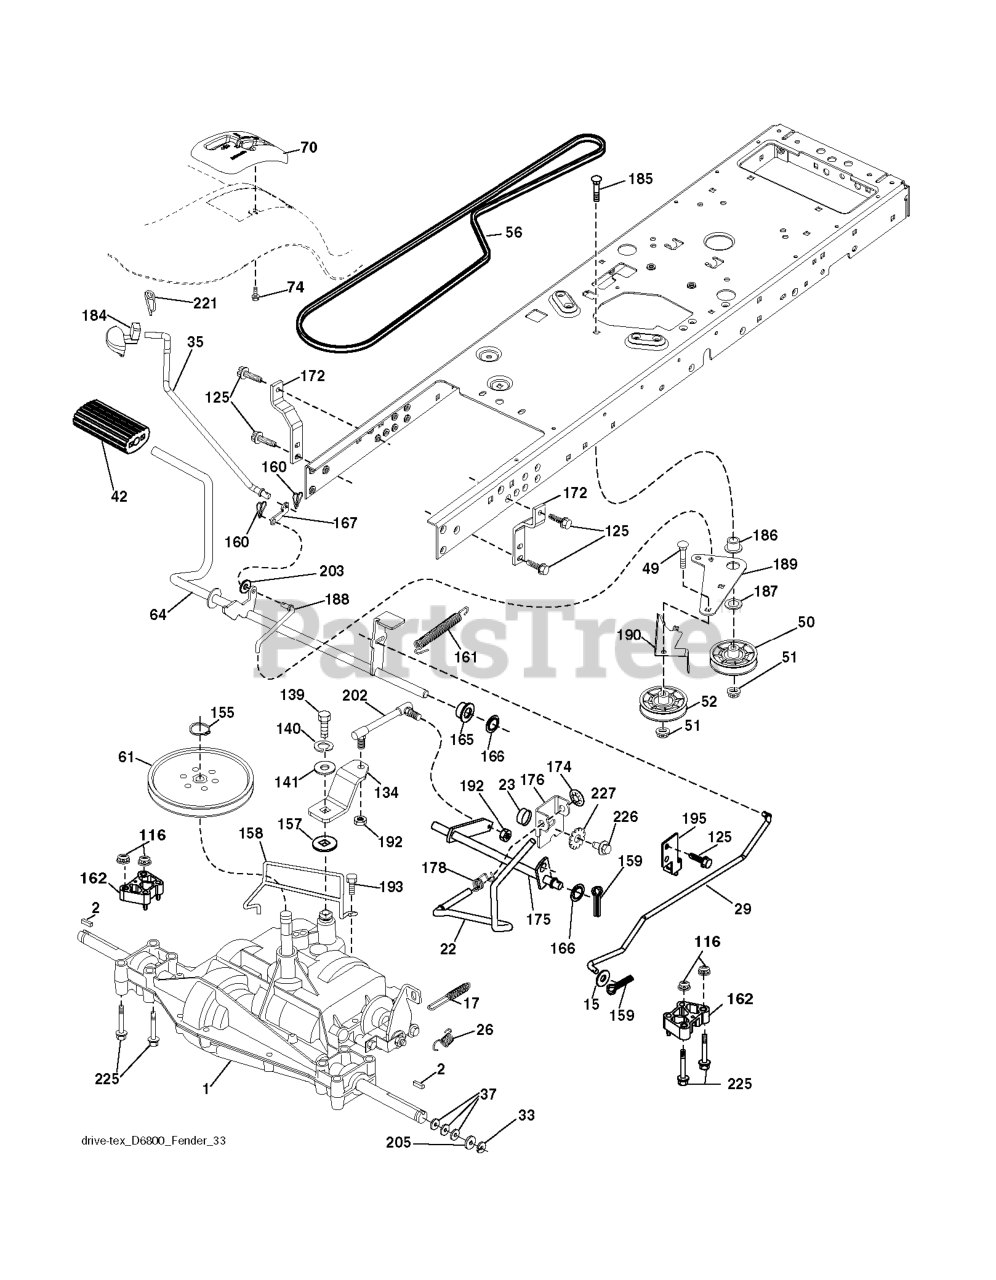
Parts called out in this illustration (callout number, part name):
2	SQUARE KEY
15	WASHER
17	SPRING.BRAKE.PEERLESS.TEX
22	ROD.SHIFT.FENDER.TLT.2006
23	KNOB.DUCKHEAD.1/2
26	SPRING.BRAKE.RTN.GR.DR
29	ROD.BRAKE.PEERLESS
35	ROD.CNTRL.PARK.PREDATOR.LT.TEX
42	PEDAL COVER T
50	IDLER.FLAT.910.OFFSET
51	NUT LOCK FLG 3/8-16 UNC
52	IDLER.V-GROOVE.910.OFFSET
56	V-BELT.TRACTOR.DRIVE.P
61	PULLEY TRANS
64	SHAFT.ASM.PEDAL.BRAKE.
70	CONSOLE.SHIFT.STL.6SP.GREY
74	SCREW.HI-LO.CONSOLE
116	NUT LOCK HEX FLANGE 5/16-18
125	SCREW
134	ARM.SHIFT.
139	BOLT 1/4-28X3/4
140	LOCKWASHER
155	RETAINING RING LT
157	WASH-SHFT PLT LT
158	KEEPER.PMS.18/20.D4365
159	COTTER PIN
160	RETAINER CLIP
161	SPRING.RETURN.CLUTCH.2006
162	SPACER.TRANSAXLE.18&22
165	BUSHING.SHAFT.BRAKE.HAND
166	NUT.PUSH.625.2006
167	LATCH.BRAKE.SPRING
172	STRAP.TRQ.LH.GEAR.DRIV
174	NUT.PUSH.500.2006
175	SHAFT.ASM.SHIFT.
176	ARM.CLEVIS.ROD.SHIFT
178	SPRING.SHIFT.GT2006
184	HANDLE PARKING BRAKE
186	SPACER.RETAINER
187	WASHER 12/32X2X10GA
188	RP.LINK.CLUTCH.GROUND.DRIVE
189	BELLCRANK.GROUND.DRIVE.TEX.
190	KEEPER.BELLCRANK.DRIVE
192	NUT LOCK CENTER 1/4 -28 FNTHD
193	SCREW 5/16"
195	BRKT.ROD.BRAKE.PEERLES
202	LINK.TRANSAXLE.D6800.18/20"TEX
203	WASHER
221	RETAINER.SPRING.CLIP.H
225	BOLT.HEX.FLNG.5/16-18X3.75
226	BOLT FIN HEX 7/16-14 X 1
227	WASHER SERRATED
